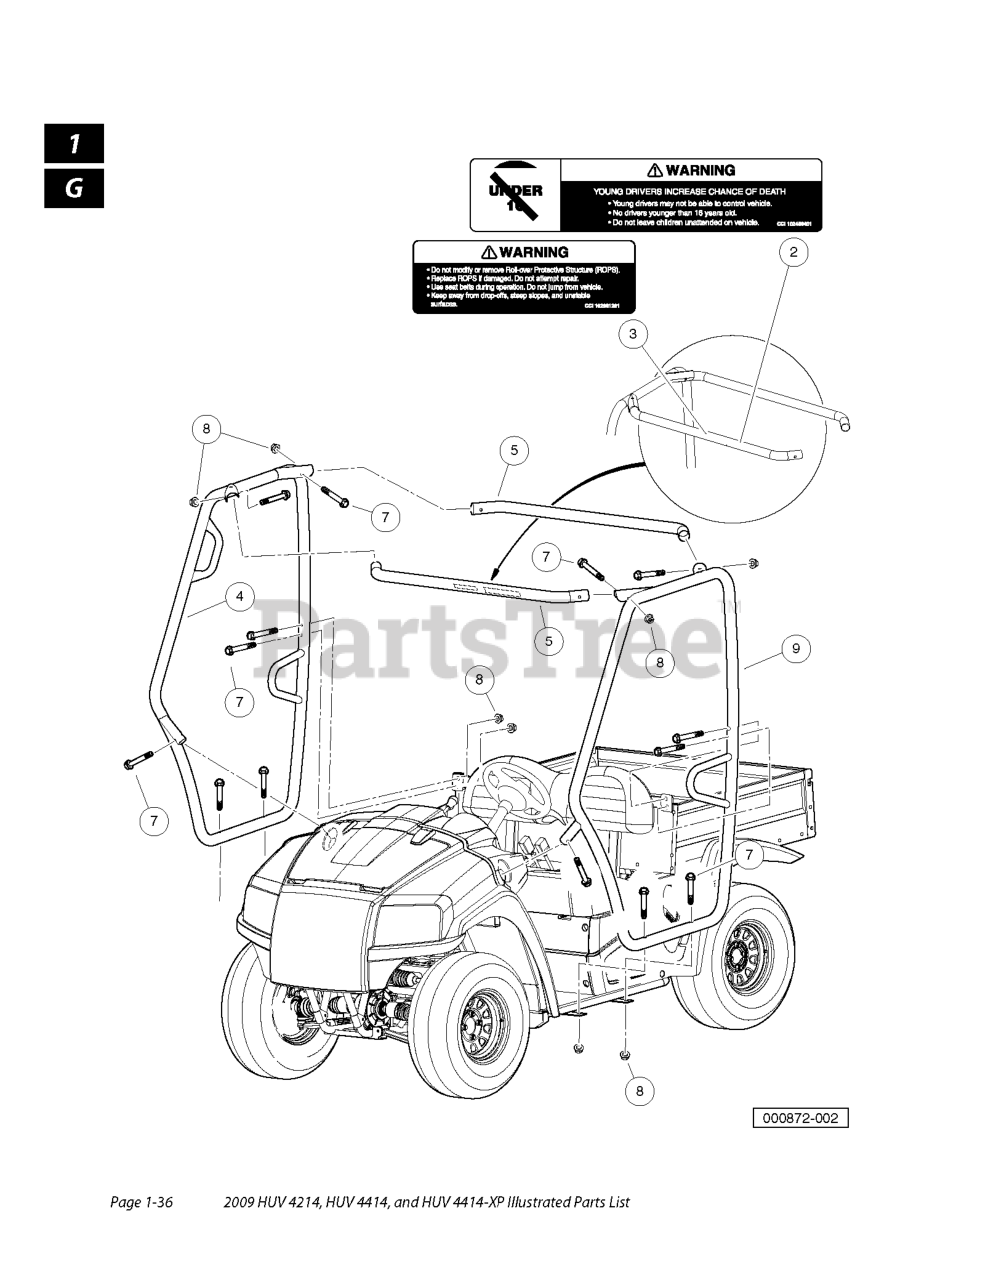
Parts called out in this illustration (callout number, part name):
1	KIT, ROPS, PASS SIDE
2	DECAL, WARNING UNDER 16
3	DECAL, WARNING, AWD ROPS
6	KIT, ROPS, DRV SIDE
7	BOLT, FLANGED, M10 X 1.5 X 65
8	NUT, FLANGED, M10 X 1.5, BLACK
9	KIT, ROPS, DRV SIDE
